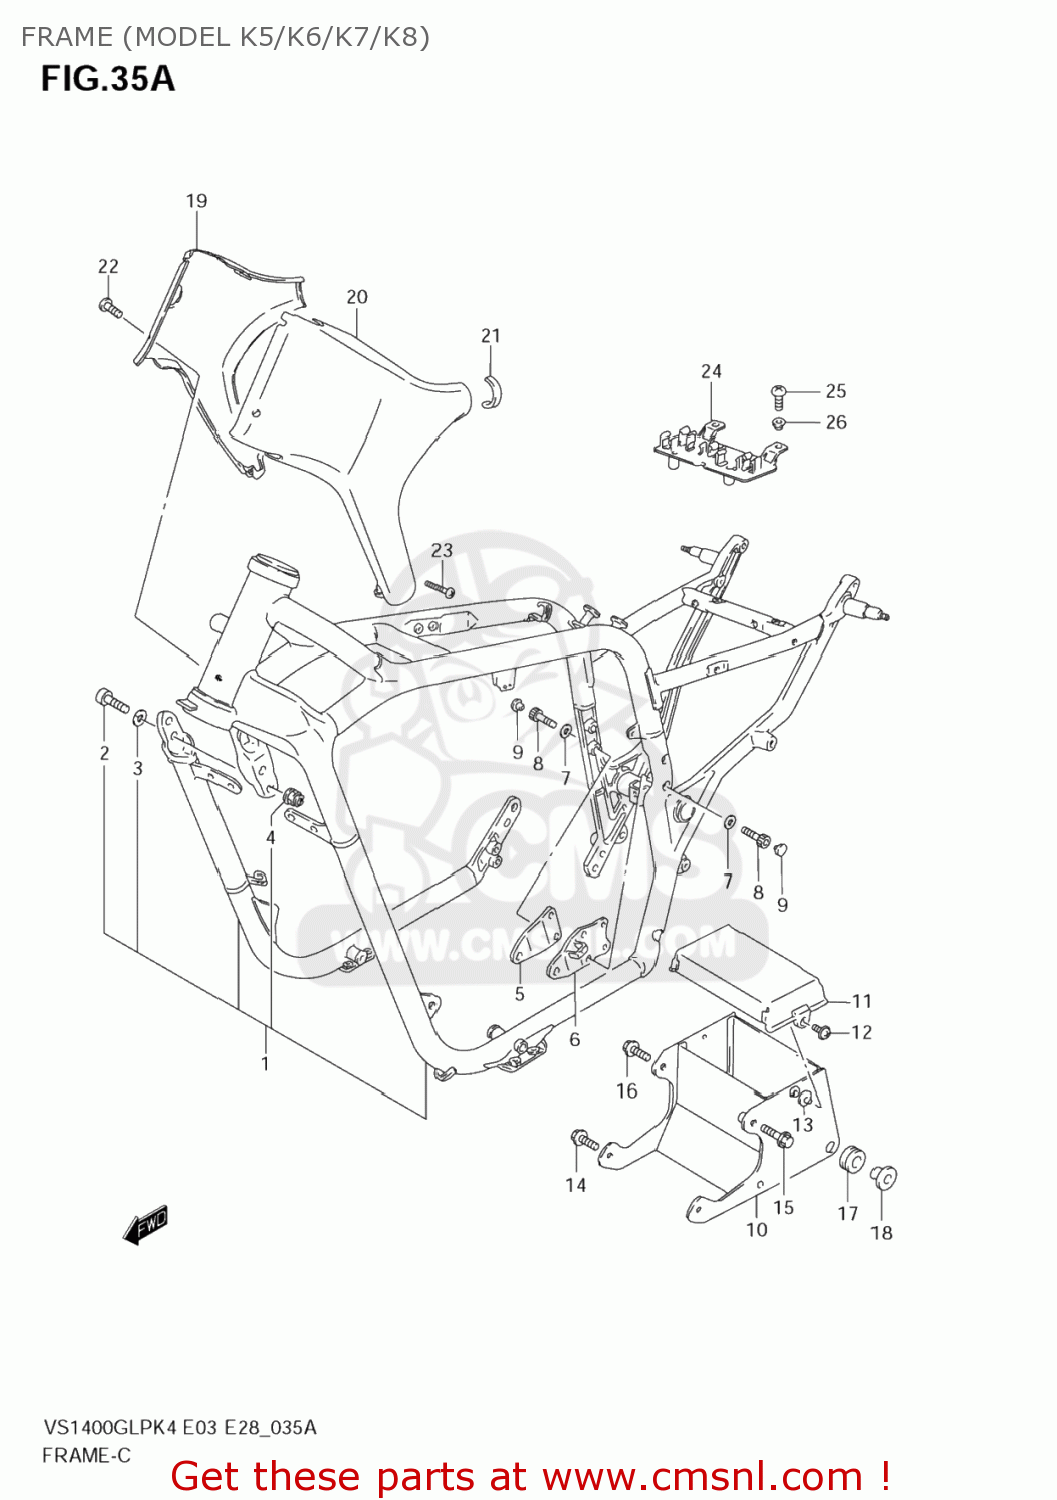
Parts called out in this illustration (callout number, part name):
1	FRAME(RED)
2	BOLT(10X33)
3	WASHER
4	NUT
5	PLATE,ENG MTG NO.4,R
6	PLATE,ENGINE MOUNT NO.4,L
7	WASHER
8	BOLT(8X32)
9	CAP(OD:14.5)
10	HOLDER,BATTERY
11	COVER,BATTERY
12	SCREW(5X12)
13	WASHER
14	BOLT
15	BOLT
16	BOLT(8X40)
17	CUSHION
18	BUSH
19	COVER,FRAME HEAD,R(RED)
20	COVER,FRAME HEAD,L(RED)
21	PROTECTOR,FRAME HEAD COVER
22	SCREW(6X10)
23	SCREW
24	HOLDER,COUPLER
25	SCREW
26	WASHER
